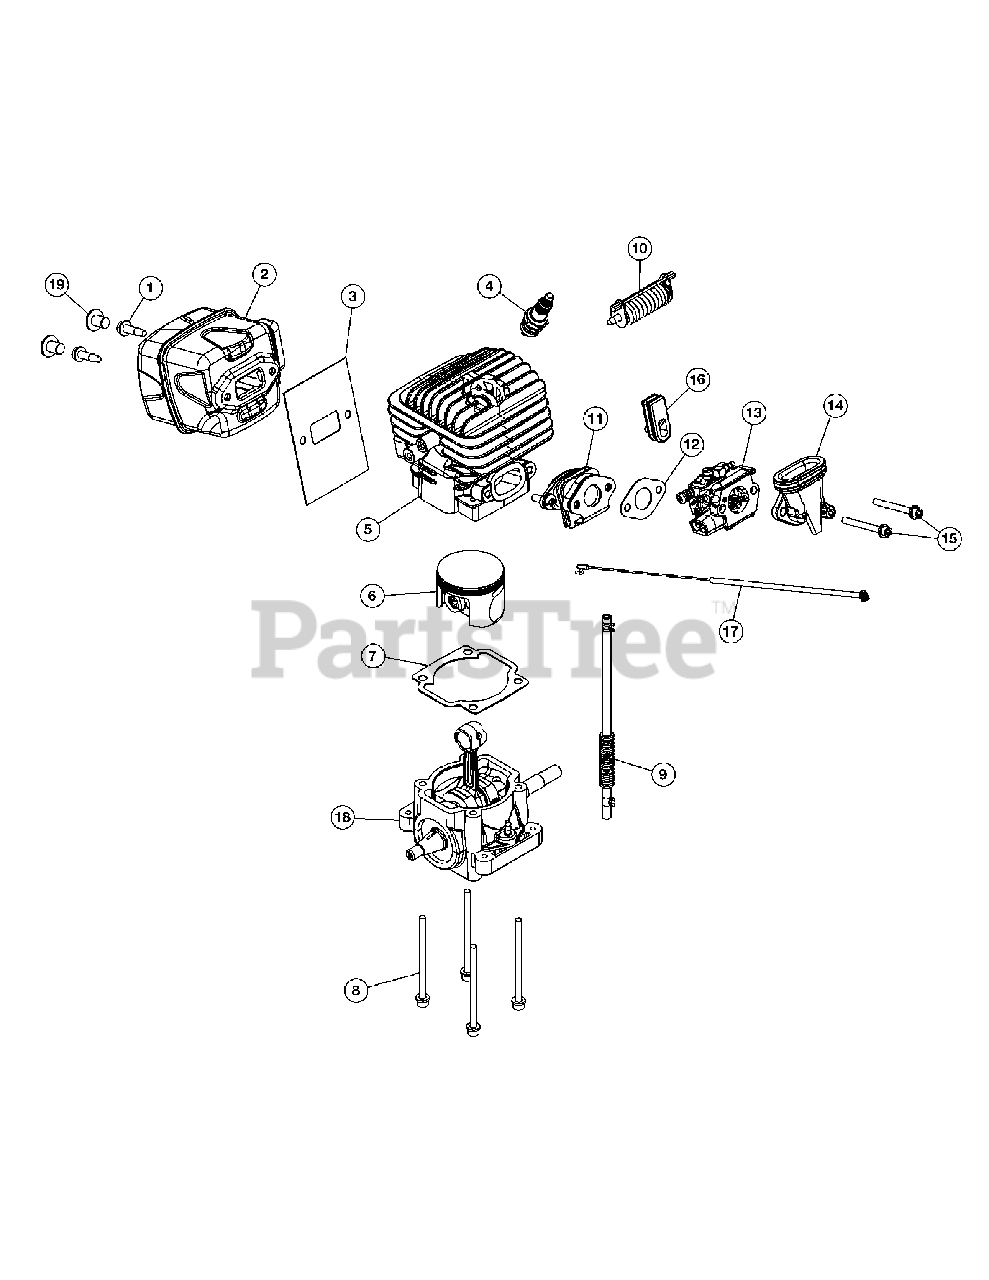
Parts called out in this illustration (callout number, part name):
1	Muffler Screw
2	Muffler Assembly (Incl. 1, 3 & 19)
3	Muffler Gasket
4	Spark Plug
5	Cylinder Assembly
6	Piston Assembly
7	Cylinder Gasket
8	Cylinder Hardware Kit (4 screws)
9	Breather Hose w/clamp
10	Isolator Assembly
11	Insulator Assembly
12	Carburetor Gasket
13	Carburetor
14	Boot & Bracket Assembly (Incl. 17)
15	Carburetor Hardware Kit (2 screws)
16	Grommet, Throttle Cable
17	Throttle Cable
18	Shortblock Assembly (Incl. 2 - 10)
19	Muffler Plug
